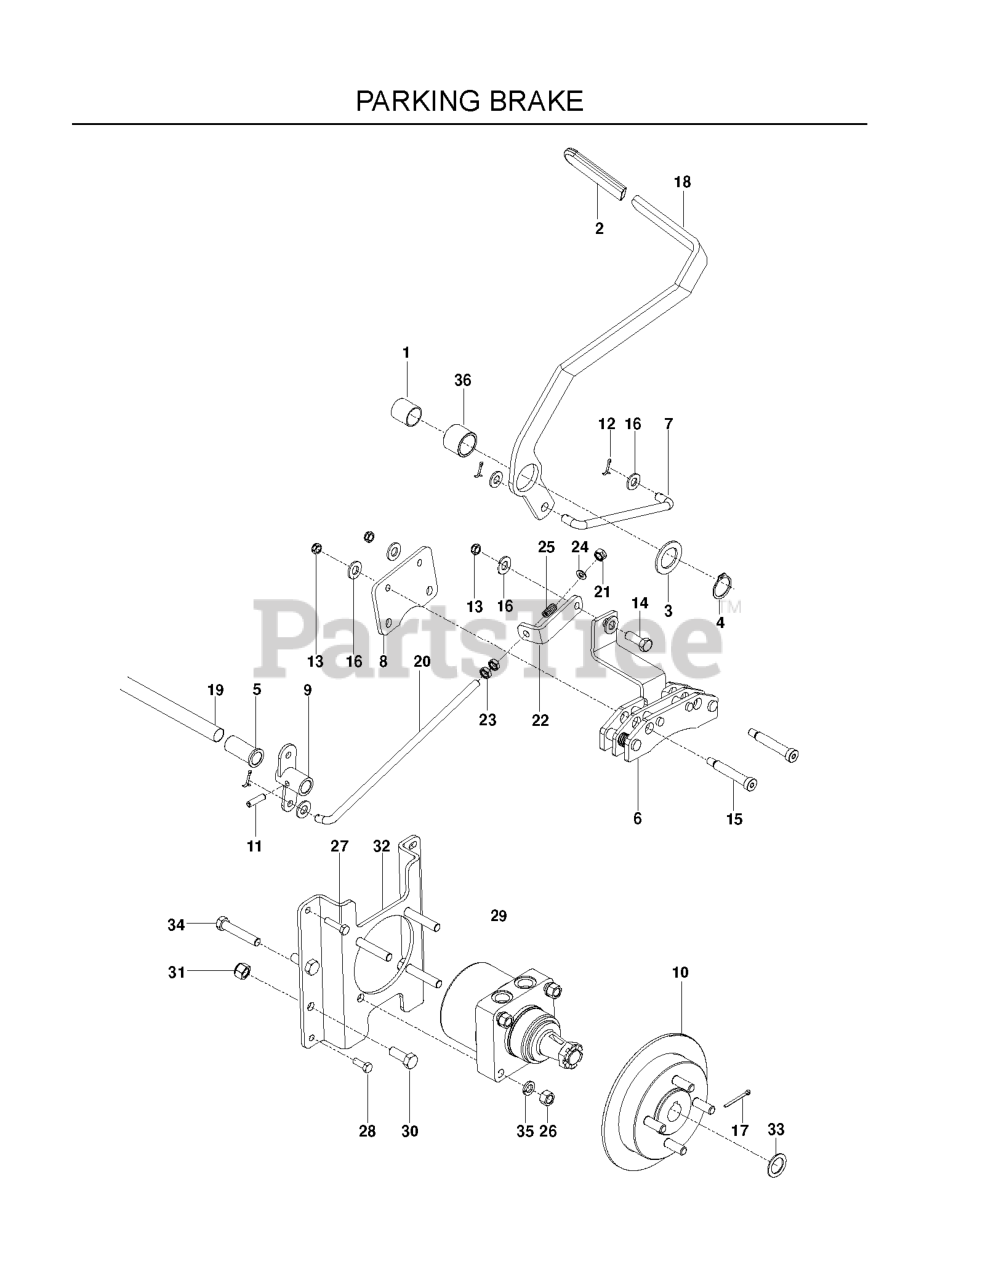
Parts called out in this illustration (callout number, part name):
2	GRIP, PARK BRAKE
3	RETAINING RING, 7/8"
4	BSHG .875 X 1.375 X .074 ZD
5	BUSHING, POLYMER 3/4X2
7	LINKAGE, BRAKE
8	PLATE, BRAKE
9	BELLCRANK, BRAKE
11	5/16 DIA ROLL PIN
12	COTTER PIN 3/32 X 3/4
13	NUT HEX 3/8-16 NYLON, THIN
14	HCS 3/8-16X1.GRD.5.ZD
15	SB 3/8-16 X 2-1-1/2 SKT HDD ZD
16	WASHER 3/8 SAE FLAT
17	PIN COTTER 4MM X 45MM
18	BRAKE LEVER WLDMT
20	LINKAGE, REAR BRAKE
21	NUT 3/8F CENTERLOCK
22	BRACKET, L
23	NUT 3/8-24 JAM
24	WASHER 3/8 SAE FLAT
26	NUT HEX 1/2
27	HCS 3/8C X 1 1/4 GR5
28	HCS 3/8C X 2 1/4
29	TL15 WHEEL MOTOR
30	HCS 1/2C X 1 1/4 SERRATED HEAD
31	NUT 1/2-13 HEX NYLOC ZD
32	MOUNT, MOTOR, WHEEL - BLK
33	MACHINE BUSHING
34	HCS 1/2C X 2 3/4
35	WASHER 1/2" SPLIT LOCK
36	BRAKE LEVER TUBE
